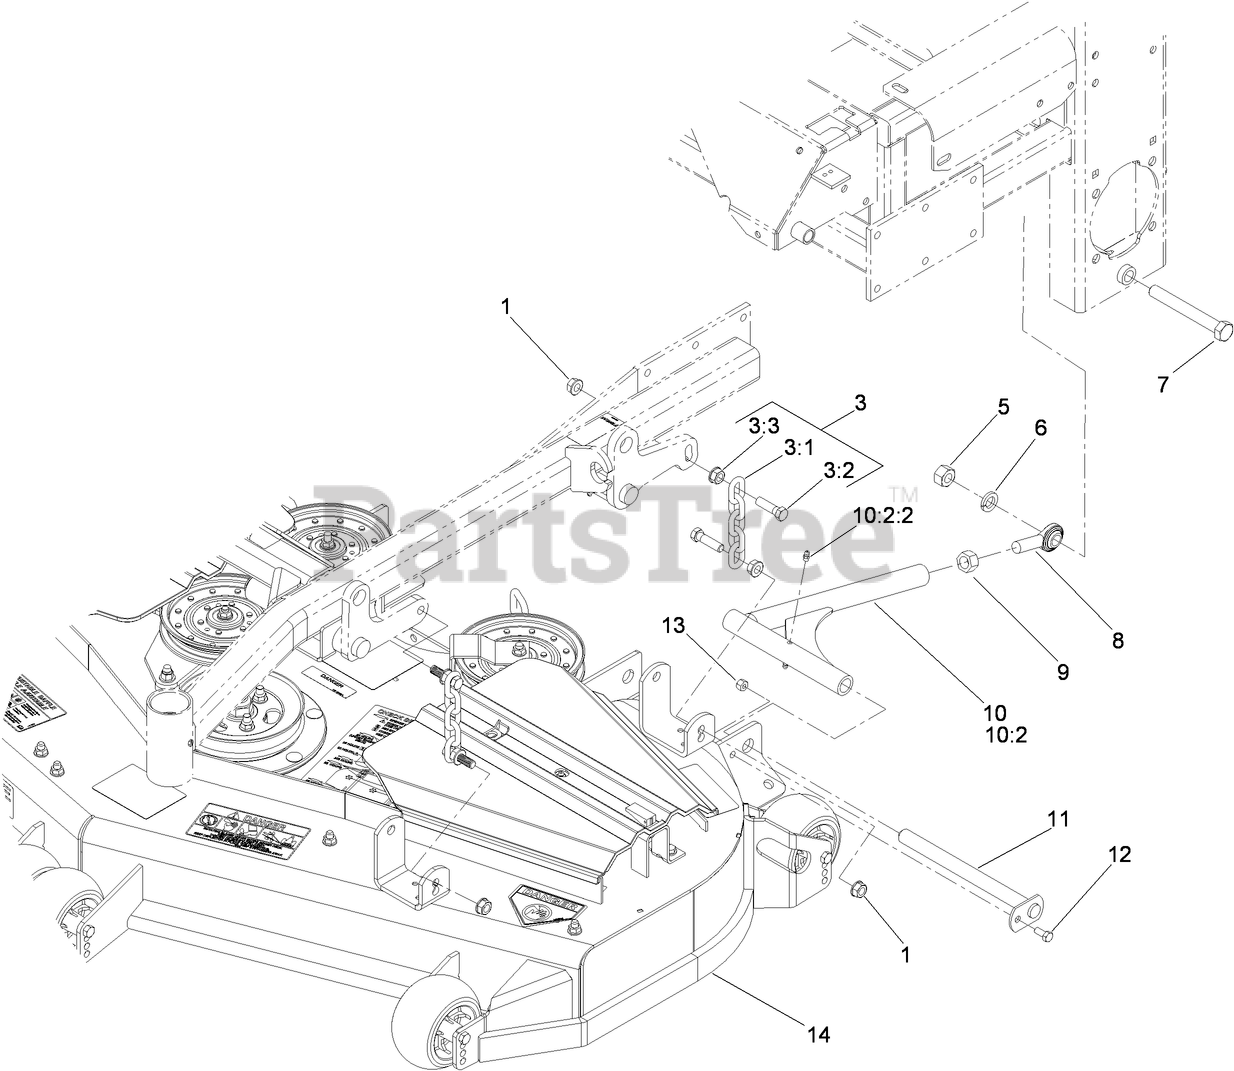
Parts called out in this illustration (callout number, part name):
1	NUT-HF
3	DECK CHAIN ASM
3:1	CHAIN-LIFT, DECK
3:2	SCREW-HH
3:3	NUT-HF
5	NUT-HEX
6	WASHER-LOCK
7	SCREW-HH
8	BALLJOINT-SPHERICAL
9	NUT-HEX
10	STRUT-DECK
10:2	TUBE AND ZERK ASM
10:2:2	FITTING-GREASE
11	PIN-STRUT
12	SCREW-HH
13	NUT-LOCK, NI
14	DECK ASM
